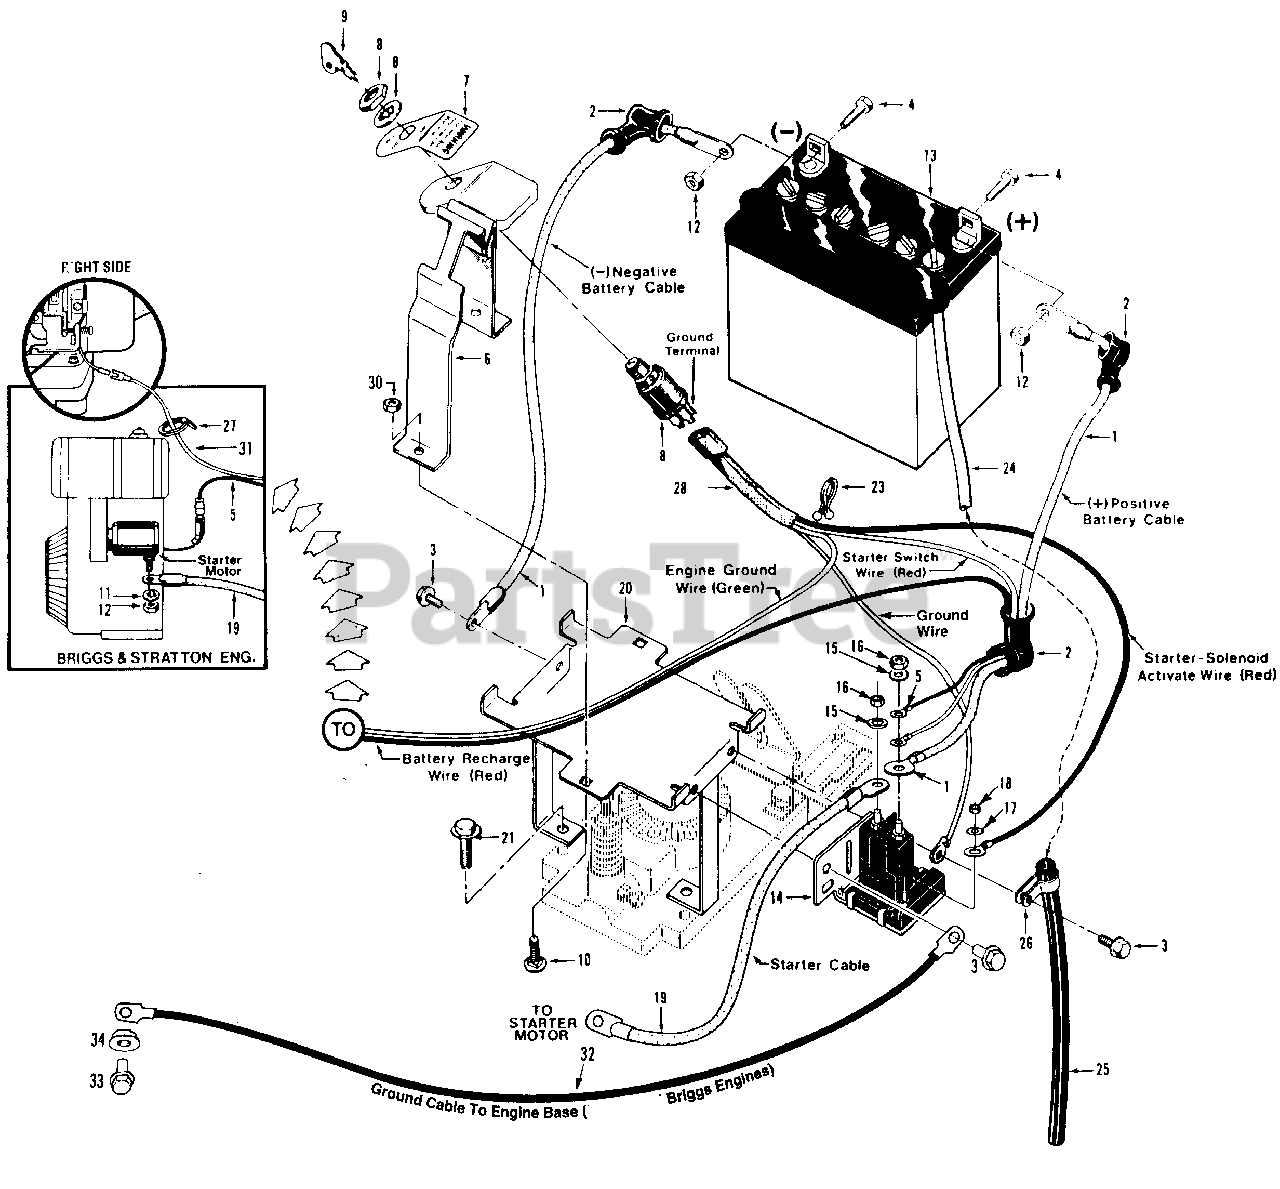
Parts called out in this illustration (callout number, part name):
1	Cable-battery, positive and negative terminals
2	Boot-terminal insulating
3	Screw-self-threading, 1/4-20 x 1/2"
4	Bolt-hex hd., 1/4-20 x 5/8"
5	Wire-recharge (red) for Briggs and Stratton engine
6	Battery Hold-down Clamp-with attached Key Switch Plate
7	Decal-ignition switch instruc
8	Key Switch
9	Key-ignition, one pair
10	Bolt-carriage, 1/4-20 x 1-1/4"
11	Lockwasher-spring lock, 1/4"
12	Nut-hex, 1/4"-20
13	Battery-12 volt, 30 amps., side-vented.
14	Solenoid-starter
15	Lockwasher-5/16"
16	Nut-hex, 5/16"-24
17	Lockwasher-external tooth, #10
18	Nut-hex, #10-32,
19	Cable-solenoid to starter motor
20	Battery Bracket
21	Bolt-flanged hex hd., 3/8-16 x 1-1/2"
23	Tie-plastic, wire retaining
24	Vent Tube-5/16" diameter
25	Shield-vent tube, 1/2" diameter
26	Clamp-vent tube shield
27	Tie-plastic
28	Wire Harness & Connecting Terminal Assy For Briggs & Stratton engines
30	Locknut-hex, 1/4"-20
31	Wire-ground
32	Cable-ground, solenoid to engine block
33	Bolt-flange lock, 5/16-18 x 1"
34	Nut-flange lock, 5/16"-18
